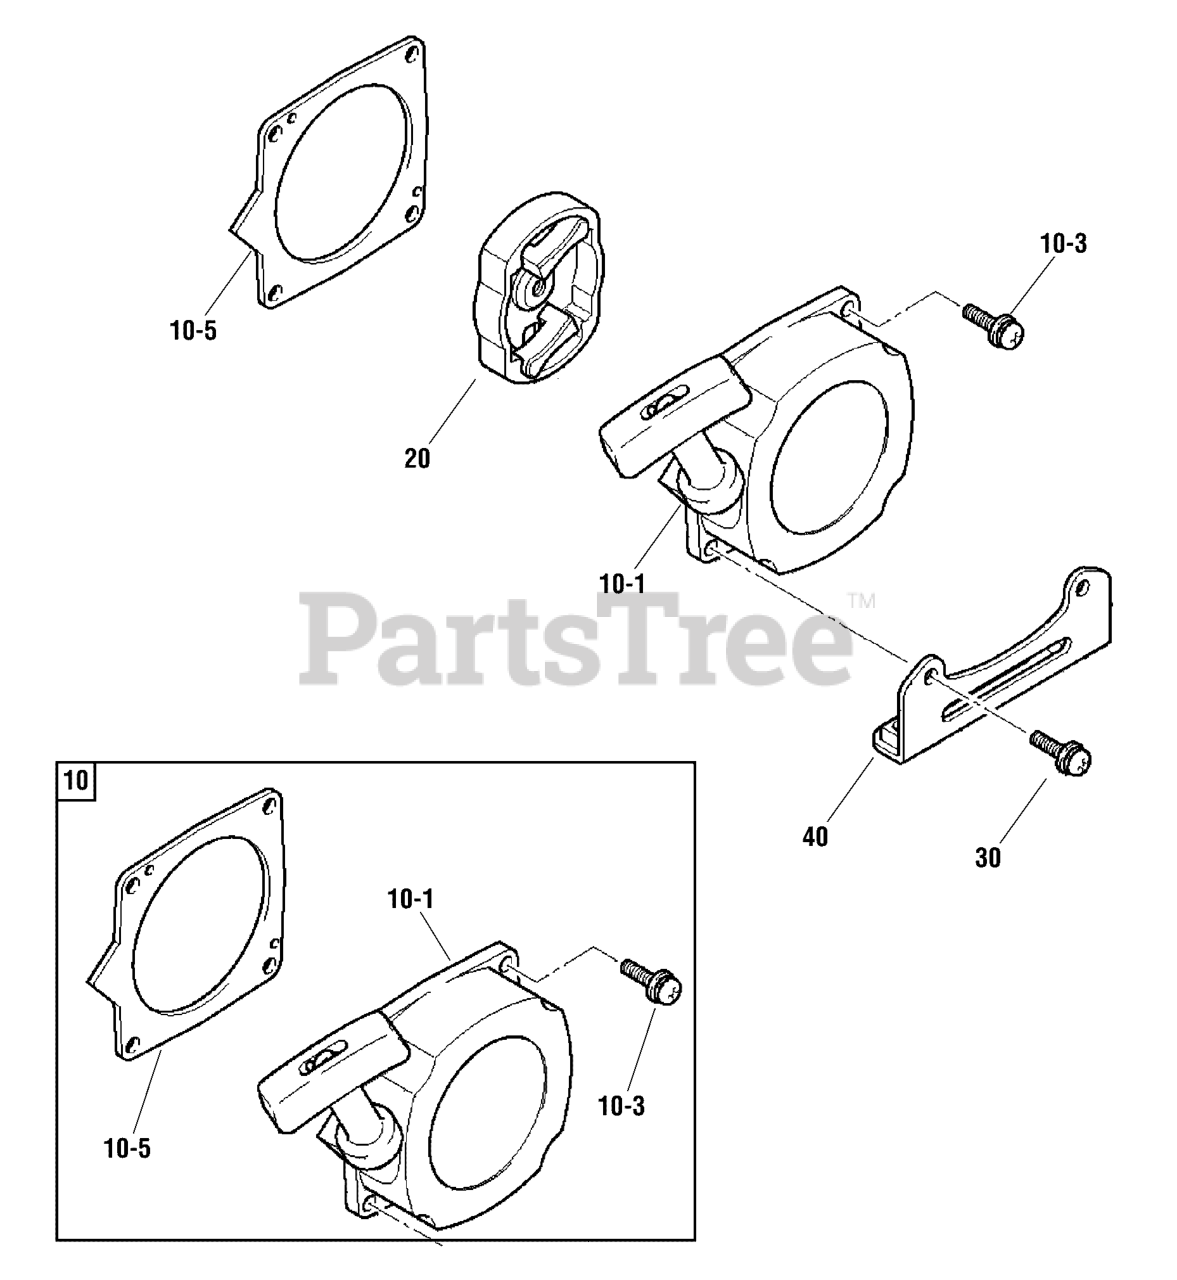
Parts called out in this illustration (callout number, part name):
10	STARTER KIT
10-1	RECOIL STARTER
10-3	SCREW & WASHER
10-5	PLATE
20	PULLEY, Starter
30	SCREW & WASHER
40	BRACKET, Tank
